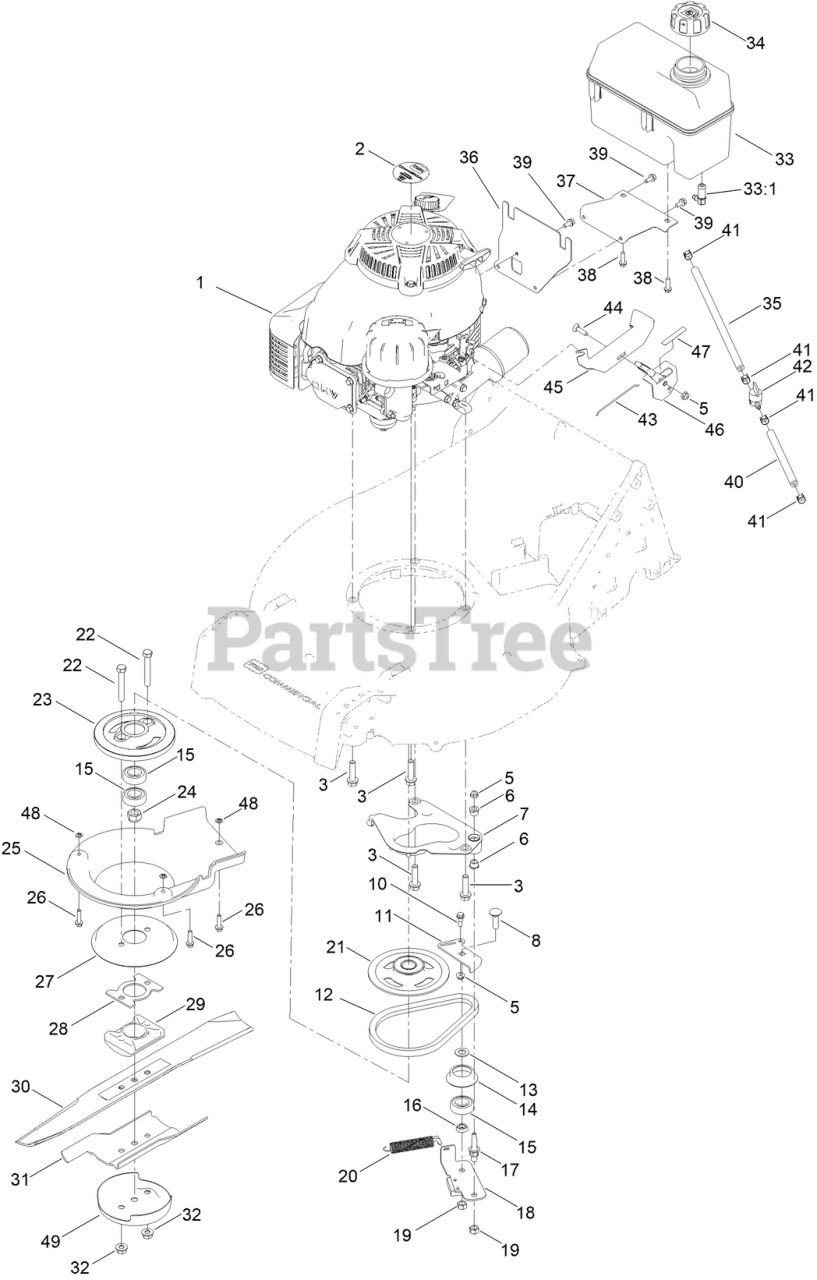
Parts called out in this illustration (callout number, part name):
3	SCREW-HWH
5	NUT-HF
6	BUSHING-FLANGE
7	PLATE-ANCHOR
8	BOLT-CARR
10	BOLT-SHOULDER
11	PLATE-GUIDE, BBC
13	SPACER
14	RETAINER-BELT
15	BEARING-BALL
16	SPACER-BEARING
17	BOLT-SHOULDER
18	PLATE-BRAKE
19	NUT-HEX
20	SPRING-TENSION, BRAKE
21	PULLEY
22	SCREW-HH
24	NUT-HEX
26	SCREW-HWHTF
28	SPACER-DRIVER, BLADE
29	SUPPORT-BLADE
30	BLADE-21IN, RECYCLING
31	ACCELERATOR-BLADE
32	NUT-FLANGE, LOCK
33	TANK-FUEL
33:1	FITTING-PLASTIC
34	CAP-GAS
35	HOSE-FUEL
36	BRACKET-TANK, MOUNTING
37	BRACKET-TANK, SUPPORT
38	SCREW-HWH
39	SCREW-HWH
40	HOSE-FUEL
41	CLAMP-HOSE
42	VALVE-FUEL
43	WIRE-CONTROL
44	SCREW-CARR
45	BRACKET-MOUNT, THROTTLE
46	CONTROL-THROTTLE
47	DECAL-THROTTLE, CHOKE
48	PUSHNUT-RETAINER, BOLT
49	CUP-ANTI SCALP
